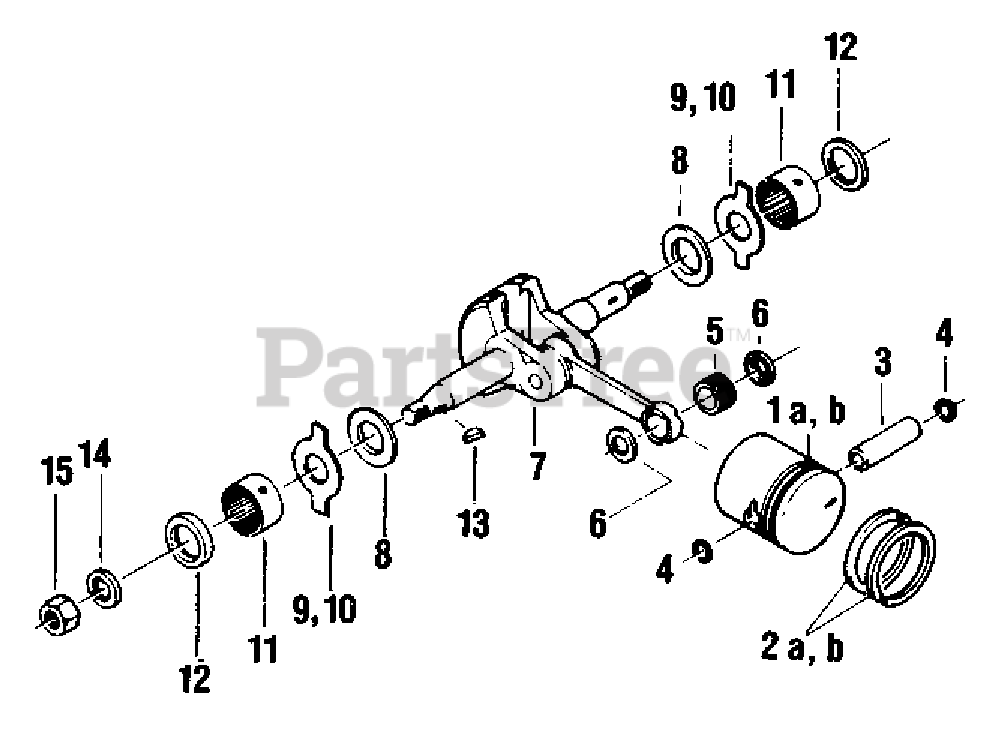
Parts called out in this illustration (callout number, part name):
1A	PISTON
1B	PISTON
2A	RING, PISTON
2B	RING, PISTON
3	PIN, PISTON
4	RING, RETAINING
5	BEARING, NEEDLE
6	WASHER, THRUST
7A	CRANKSHAFT ASSY
7B	CRANKSHAFT ASSY
8	WASHER, THRUST
9	PLATE, SIDE
10	PLATE, SIDE - RED
11	BEARING, NEEDLE
12	SEAL, OIL
13	KEY - 3X10
14	LOCKWASHER - 8
15	NUT
